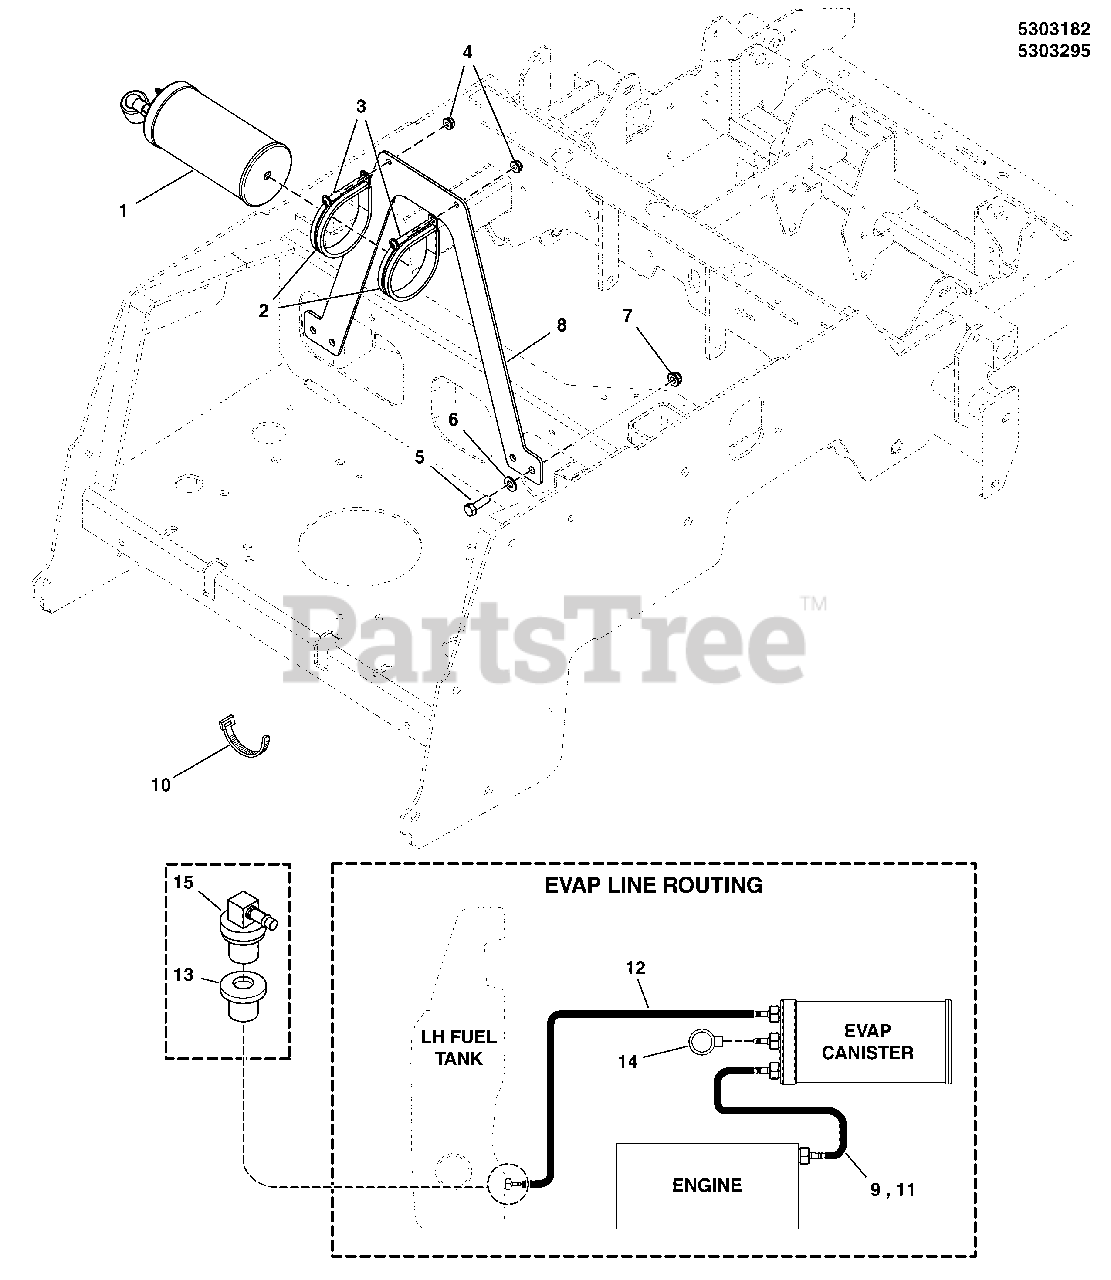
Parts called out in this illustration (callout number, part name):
1	CNSTR, CARB, 6 GAL
2	CLAMP, 3" ID, CUSHIONED, STAINLESS
3	SCREW, 1/4-20 X 3/4, ALLEN BH, CZ
4	NUT, 1/4-20 HEX NYLOCK FLANGE (5025391)
5	BOLT, 5/16-18 X 1 GD5 YZ
6	WASHER, 5/16 SAE
7	NUT, 5/16-18 HEX NYLOCK FLANGE
8	PLATE, MOUNT, CANISTER, IS700 - BLK
9	HOSE, VAPOR, 5MM ID, 27.00 LG
10	TIE, SELF-LOCKING, 12"
11	HOSE, VAPOR, 5MM ID, 38.00 LG
12	HOSE, VAPOR, 5MM ID, 18.00 LG
13	GROMMET
14	DUST FILTER, CANISTER
15	ASSEMBLY, REMOTE VENT - NO VALVE
